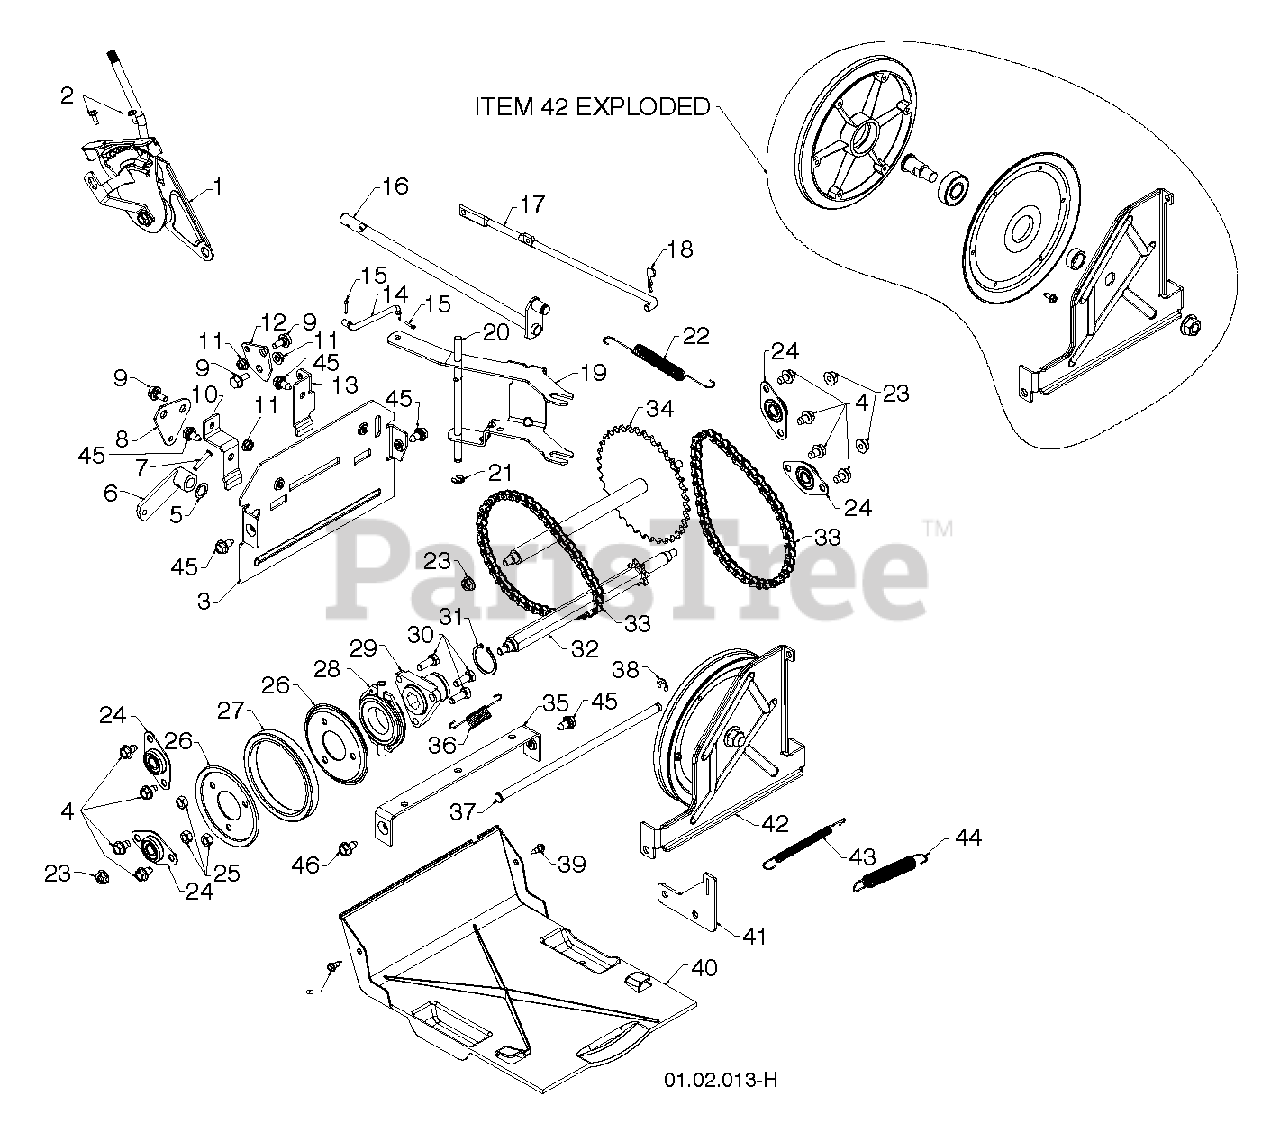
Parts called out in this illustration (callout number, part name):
2	SCREW
3	PLATE.END.CHAIN.ASM.YELLOW
4	SCREW LT
5	THRUST WASHER
6	ARM, AUGER CONTROL
7	CLEVIS PIN
8	PLATE.SHIFTER.BZP
9	BOLT.SHOULDER.3/X.25
10	Shifter Plate Bracket, Bzp
11	NUT.HEX.FLANGE.1/4
12	Clutch Plate
13	Clutch Bracket Plate
14	LINK, SPEED CONTROL
15	RETAINER CLIP
16	CONTROL.SHAFT.ASM
17	ROD.CLUTCH.SWING.PLATE
18	SPRING RETAINER
19	SHIFTER BRACKET
20	ROD.PIVOT.SHIFTER
21	KLIP RING TI
22	SPRING.TRACTION.RETURN
23	NUT.LOCK.5/16-18
24	BEARING FLANGE BALL
25	NUT.CENTERLOCK.5/16-
26	PLATE.RUBBER.WHEEL
27	RING.RUBBER.4.5".SNOW.DR(2 2MC
28	TRUNNION BEARING ASSY
29	HUB, RUBBER WHEEL
30	BOLT
31	Retaining Ring
32	SHAFT.HEX.W/SPOCKET
33	CHAIN.DRIVE.SNOWTHROWER.#420
34	SPROCKET.WELDMENT
35	BRACKET.YOKE.SHIFTER.BLACK
36	SPRING, BIAS
37	ROD.PIVOT.SWING.PLATE.SNOW
38	E-RING.RETAINER.REINFORCED.375
39	SCREW, HEX HEAD, TAPPING
40	PAN.BOTTOM.PLASTIC
41	BRACKET.TRACTION.SPRING.
42	Drive Plate Pulley Assembly
43	SPRING.TRACTION.IDLER
44	SPRING, BRAKE
45	BOLT.HEX.HD.WASHER.5/16-18X.75
46	BOLT.5/16HEX.WHS.HD
